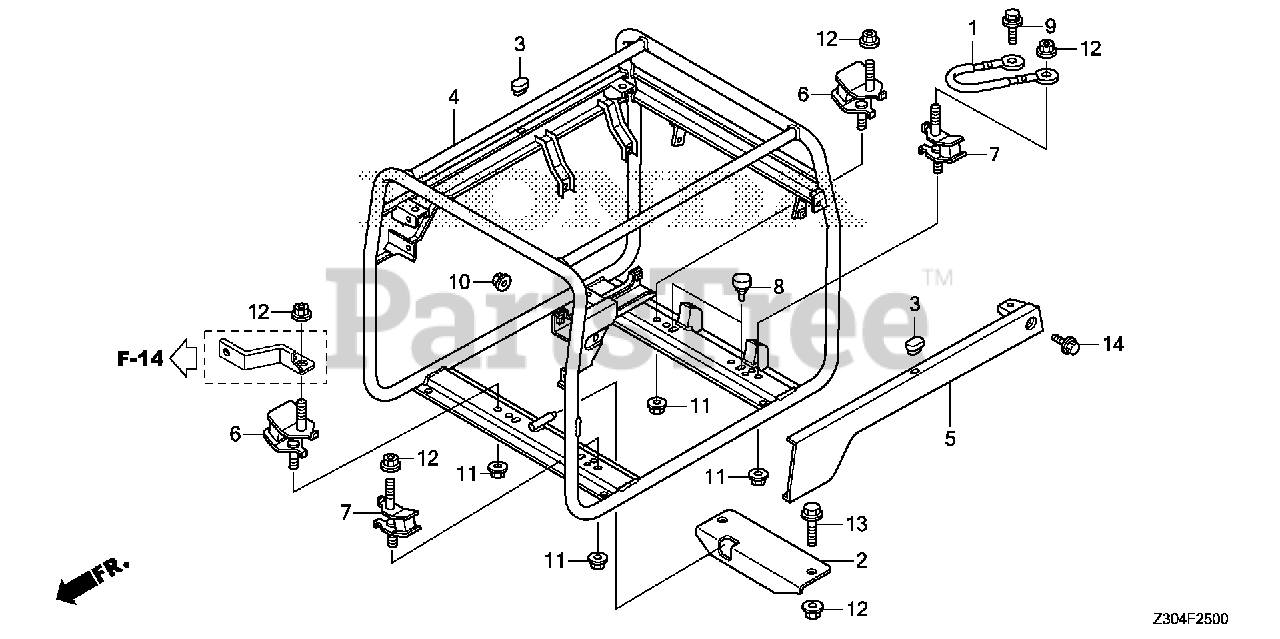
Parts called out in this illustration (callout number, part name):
1	CABLE, SUB-GROUND
2	BRACKET, STOPPER
3	RUBBER, FUEL TANK MOUNTING
4	FRAME *NH105* (CL)(COO) (MAT BLACK)
5	FRAME, R. SIDE *NH105* (COO)(FOR U.S.A.) (MAT BLACK)
6	RUBBER (LOWER)
7	RUBBER (LOWER)
8	RUBBER, BUMP STOP
9	BOLT, GROUND (6X16) (WASHER 12.5MM) (ZN)
10	NUT, FLANGE (6MM)
11	NUT, FLANGE (8MM)
12	NUT, FLANGE (10MM)
13	BOLT, FLANGE (10X40)
14	BOLT, FLANGE (6X12)
